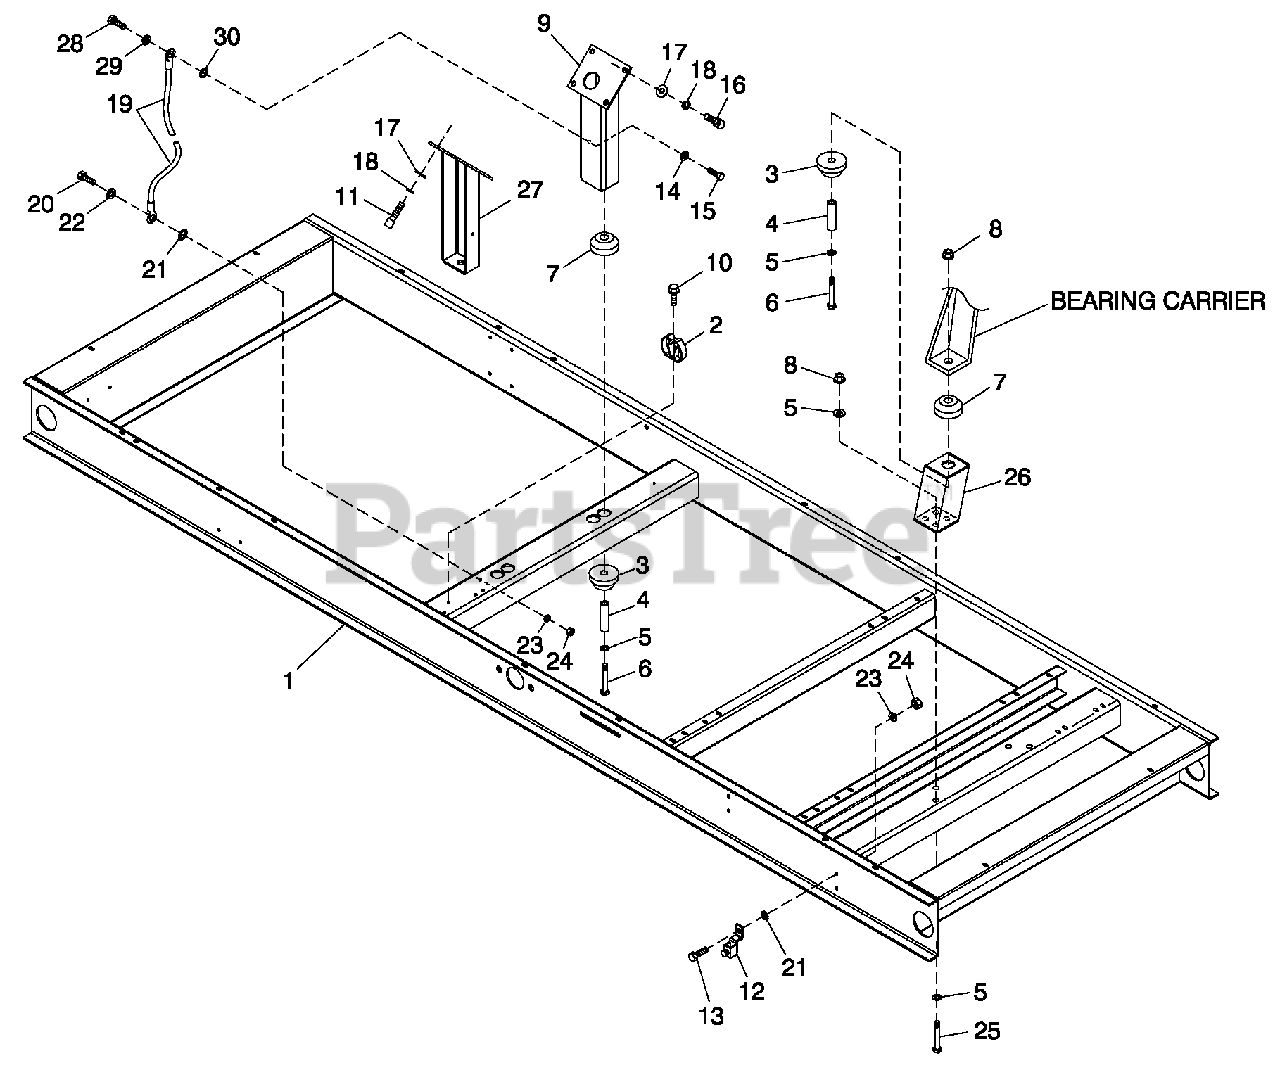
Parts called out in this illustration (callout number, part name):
1	BASE CPL 100-130KW 6.8L GB
2	SPRING CLIP HOLDER .37-.62
3	DAMPENER VIBRATION
4	SPACER .49 X .62 X 1.87 PWDR/ZINC
5	WASHER FLAT M12
6	SCREW HHC M12-1.75 X 85 G8.8
7	DAMPENER VIBRATION 50 WHITE
8	NUT LOCKING M12-1.75
9	SUPPORT ENG 5.4L LH/RH 6.8L RH
10	SCREW HHTT M4-0.7 X 8 BP
11	SCREW SHC M10-1.5 X 60 G12.9
12	LUG SOLDERLESS 3/0-#4 X 13/32 CU
13	SCREW HHC M8-1.25X 25 G8.8
14	WASHER FLAT 1/4-M6 ZINC
15	NUT HEX M6 X 1.0 G8 YEL CHR
16	SCREW SHC M10-1.5 X 30 G12.9
17	WASHER FLAT 3/8-M10 ZINC
18	WASHER LOCK M10
19	ASSY WIRE 14.00"
20	SCREW HHC M8-1.25X 30 G8.8
21	WASHER SHAKEPROOF INT 3/8
22	WASHER LOCK M8-5/16
23	WASHER FLAT 5/16-M8 ZINC
24	NUT HEX M8-1.25 G8 YEL CHR
25	SCREW HHC M12-1.75 X 40 G8.8
26	TOWER GB COMPROD C5
27	SUPPORT ENGINE 6.8L LH SIDE
28	SCREW HHC M6-1.0 X 30 G8.8
29	WASHER LOCK M6-1/4
30	WASHER SHAKEPROOF INT 1/4
